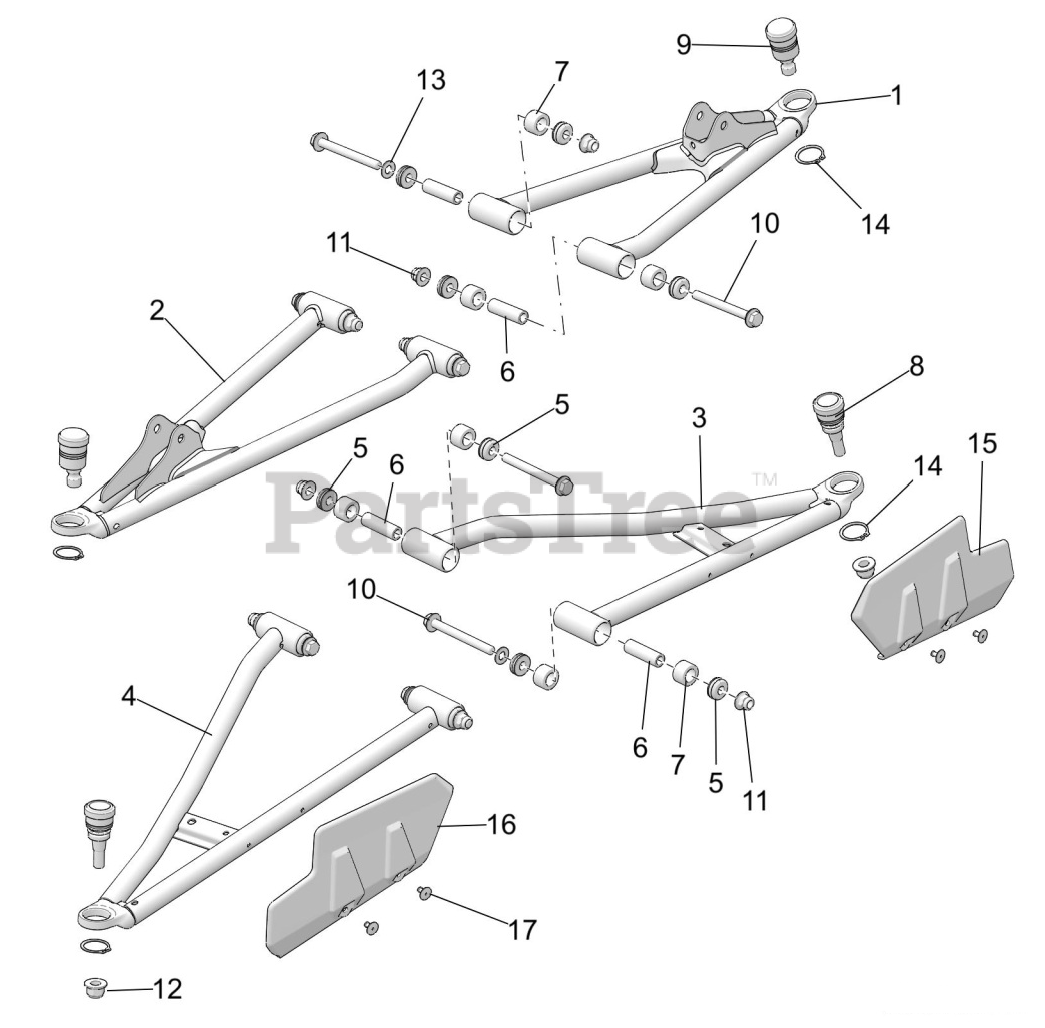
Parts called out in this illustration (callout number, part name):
1	WELD-A-ARM-FR-UPR-LH-BLK
2	WELD-A-ARM-FR-UPR-RH-BLK
3	WELD-A-ARM-FRT-LWR-LH-M-BLK
4	WELD-A-ARM-FRT-LWR-RH-M.BLK
5	ASM-PIVOT CAP- SEALED- M10
6	SHAFT-PIVOT-SHORT-M10
7	BUSHING-STANDARD-SUSP-M10
8	BALL-JOINT-M12X1.50-TAPERED
9	BALL-JOINT-10MM STUD
10	SCR-HXFL-M10X1.25X95 10.9 ZOD
11	NUT-M10X1.25-FLG-NYLOC-OLIVE D
12	NUT-M12X1.5-FLG-NYLOC-OLIVE D
13	WASHER-3/8 FW
14	RING-RETAINER-EXTERNAL-1.188
15	SHIELD-CV-FRONT-LH-BLK
16	SHIELD-CV-FRONT-RH-BLK
